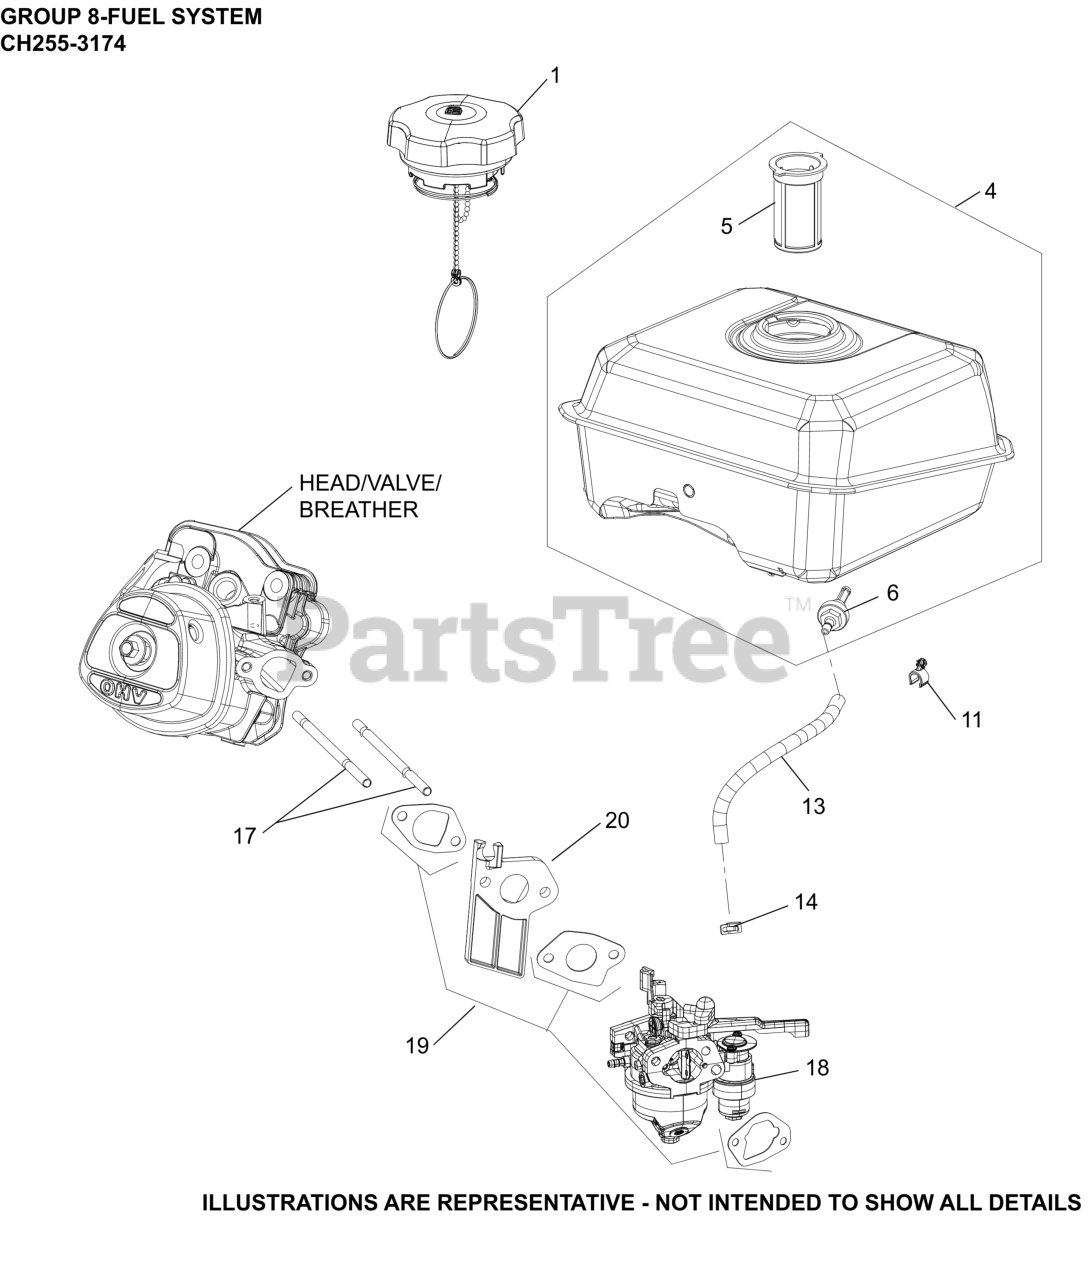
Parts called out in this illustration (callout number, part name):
1	CAP, FUEL ASSEMBLY
4	KIT, FUEL TANK ASSEMBLY
5	FILTER, FUEL TANK
6	FITTING, FUEL ASSY
11	CLIP, FUEL HOSE
13	LINE, FUEL (10"-CUT TO LENGTH)
14	CLAMP, FUEL LINE
17	STUD, CARBURETOR
18	KIT, CARBURETOR
19	KIT, INTAKE GASKET
20	INSULATOR, CARBURETOR
NI	KIT, HIGH ALT (4000-8000 FT)
NI	KIT, HIGH ALT (8,000+ FT)
